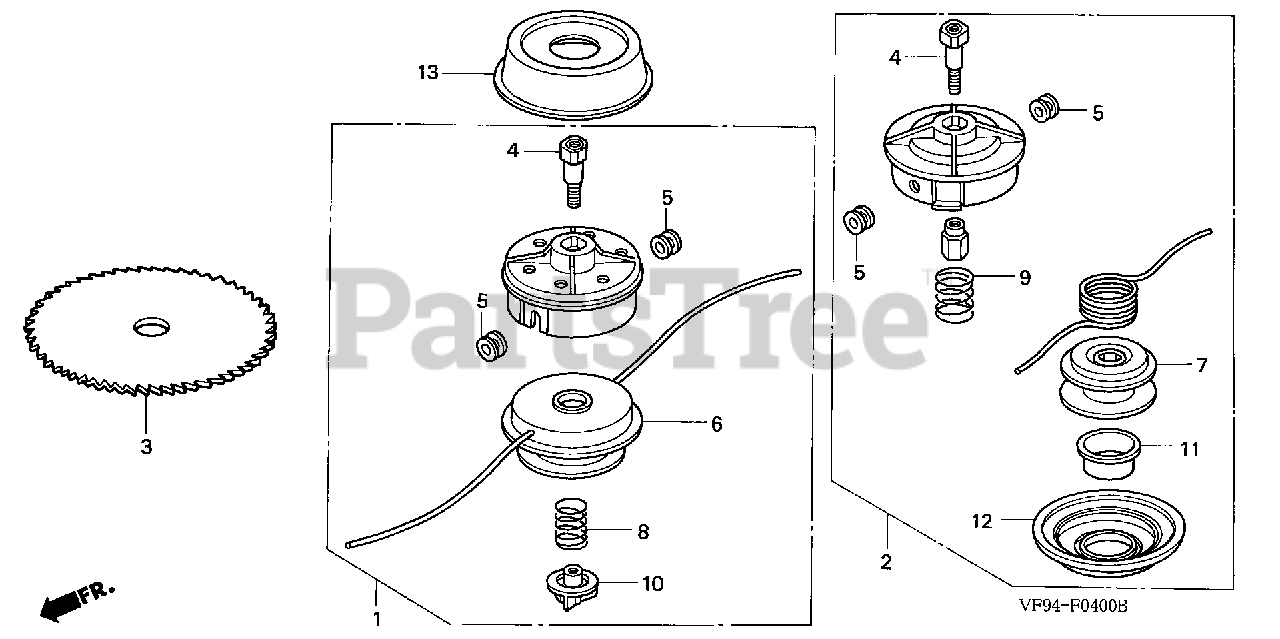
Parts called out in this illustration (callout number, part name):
2	TRIMMER HEAD, SEMI-PRO
4	SHAFT (10X1.25) (LH)
9	SPRING
